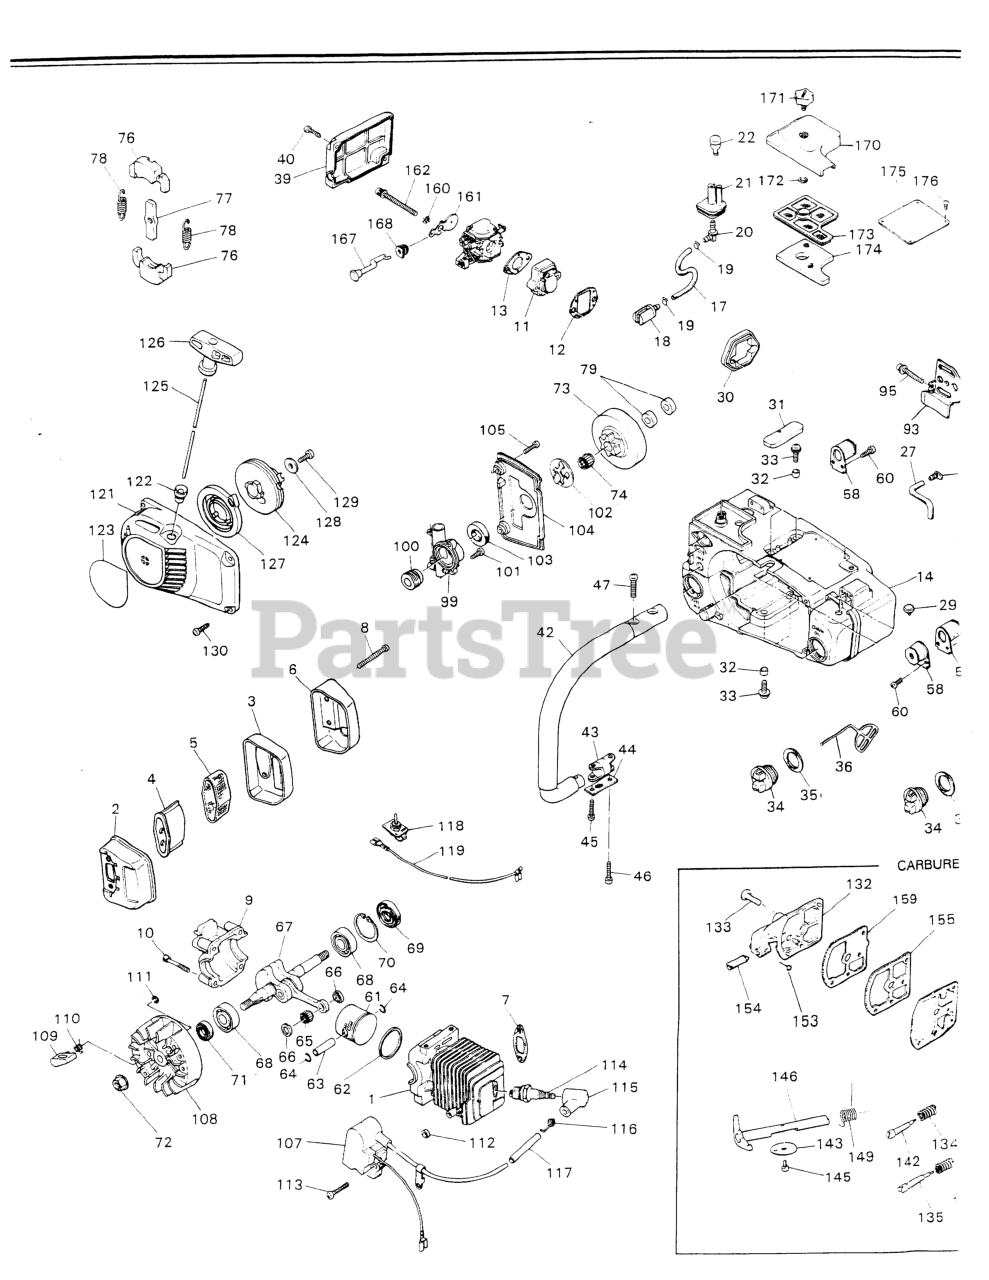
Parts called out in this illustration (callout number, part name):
3	COVER
4	BAFFLE
5	ARRESTER
7	GASKET
10	BOLT, M5 X 30
13	GASKET, CARB (USE -14121)
17	PIPE (USE -85411)
18	5500-85400 (RRLS. 1750-85300)
19	CLIP (REPLACES 2841-31280)
21	GROMMET
22	BREATHER ASSY (RPLS 2630-31270
27	PIPE (USE -85411)
29	VALVE A
35	GASKET
40	SCREW
44	STOPPER (RPLS -32150)
60	SCREW (REPLACES 50030272)
64	RING, SNAP (RPLS 1101-41320)
65	BEARING
66	WASHER, THRUST (NLA)
67	SHAFT COMP
69	SEAL, OIL
70	RING, SNAP, M32 x 1.2
74	BEARING
76	SHOE, CLUTCH
78	SPRING
100	GEAR
102	PLATE
103	SEAL
105	SCREW
111	RING, SNAP, M4
113	SCREW, M4x25 (RPLS.0260-30425)
116	SPRING
117	TUBE
118	SWITCH A
122	GUIDE (RPLS -75120)
127	HOLDER COMPLETE
130	SCREW
132	COVER (NLA)
134	SPRING (NLA)
145	SCREW (NLA)
146	SHAFT A (NLA)
153	PIECE (NLA)
155	KIT, GASKET
159	KIT, DIAPHRAGM
168	GROMMET
172	RING, SNAP, M4
174	ELEMENT
NI	MUFFLER ASSEMBLY
NI	PIPE COMP (USE -31202)
NI	PIPE ASSEMBLY
NI	HANDLE A
NI	CLUTCH ASSEMBLY
NI	ICING KIT
